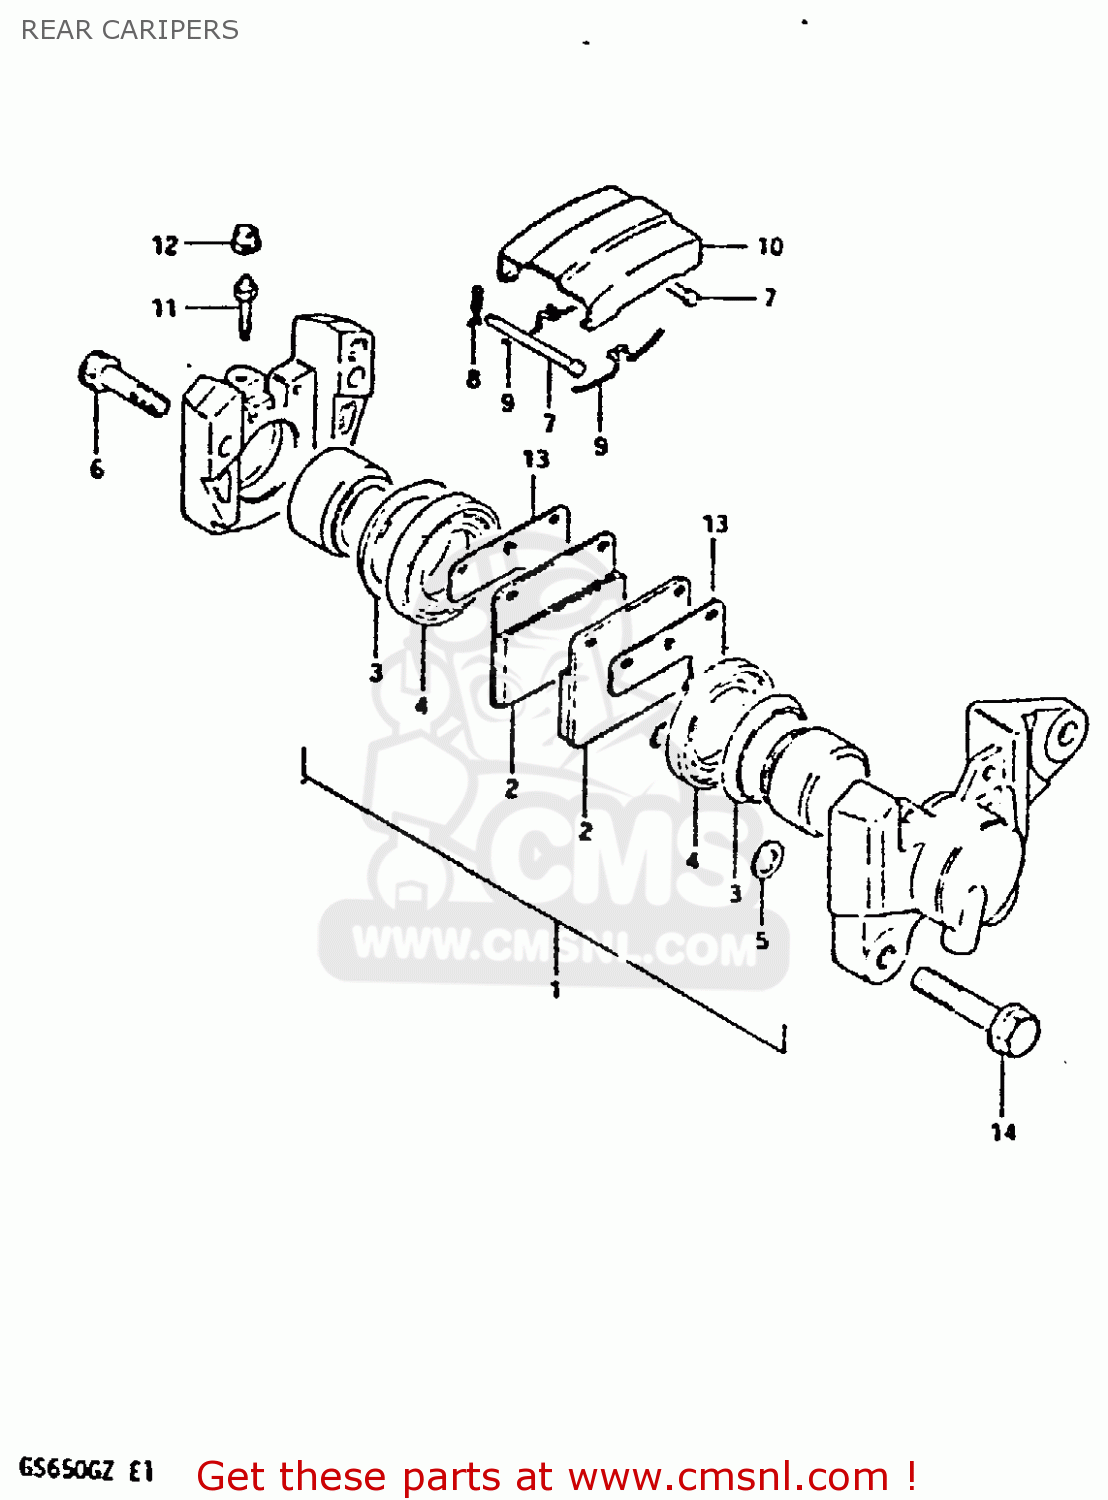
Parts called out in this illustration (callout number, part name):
1	PISTON SET
2	PAD,BRAKE
3	SEAL,PISTON
4	BOOT,PISTON
5	SEAL,JOINT
6	BOLT,CALIPER HOUSING
7	PIN,PAD
8	CLIP,PAD PIN
9	SPRING
10	COVER,DUST
11	BLEEDER
12	CAP,BREATHER
13	SHIM,RR CALIPER
14	BOLT
